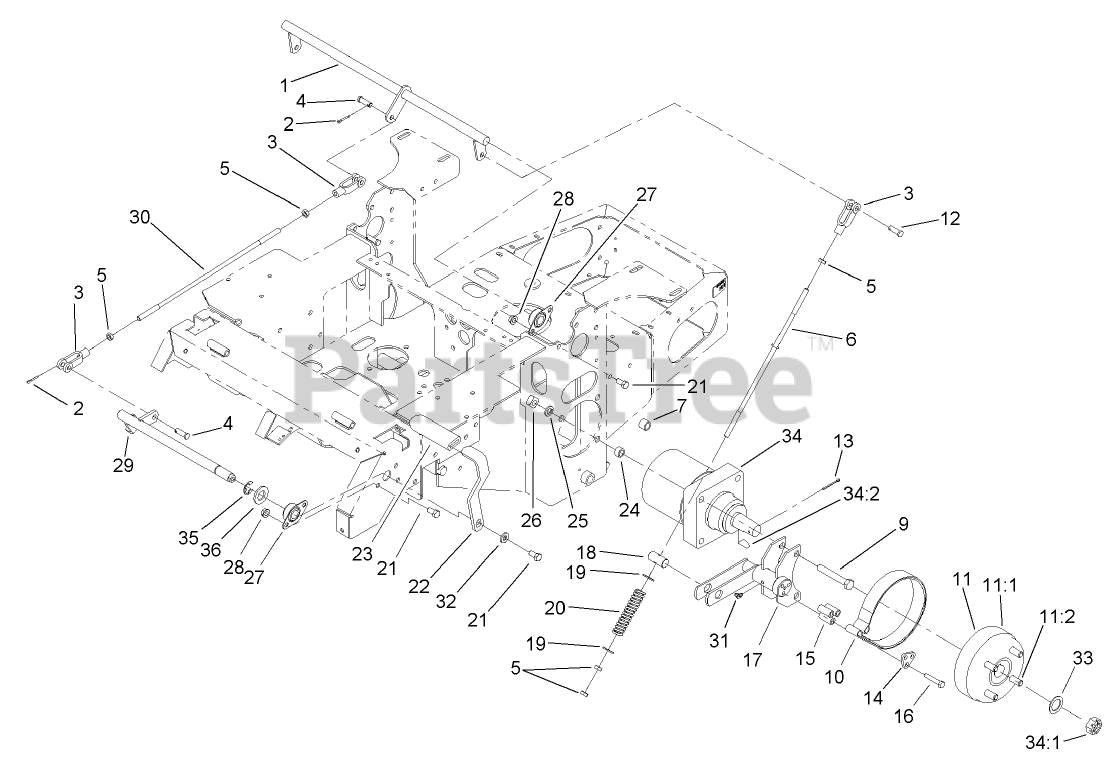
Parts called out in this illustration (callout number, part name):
1	CRANK-BRAKE, PARK
2	PIN-COTTER
3	YOKE-LINKAGE, BRAKE
4	PIN-CLEVIS
5	NUT-HEX
6	ROD-BRAKE
7	SPACER-WHEEL
9	SCREW-HH
10	BAND-BRAKE
11	WHEEL HUB ASM
11:1	HUB-WHEEL
11:2	STUD-WHEEL
12	Pin-Spring, Clevis
13	PIN-COTTER
14	RETAINER-BAND, BRAKE
15	SPACER
16	SCREW-HH
17	BRACKET-BRAKE
18	PIN-TRUNION
19	WASHER-FLAT
20	SPRING-BRAKE
21	SCREW-HH
22	HANDLE-BRAKE, PARK
23	GRIP-LEVER
24	SPACER-WHEEL
25	WASHER-LOCK
26	NUT-SQUARE
27	BEARING-FLANGE, SIDE
28	NUT-HHF, WHIZ
29	Shaft-Brake, Parking
30	LINKAGE-HANDLE, BRAKE
31	FITTING-GREASE
32	WASHER-BELLEVILLE
33	WASHER-SPACER
34	MOTOR-WHEEL
34:1	NUT-HH
34:2	KEY-WOODRUFF
35	E-RING
36	WASHER-FLAT
